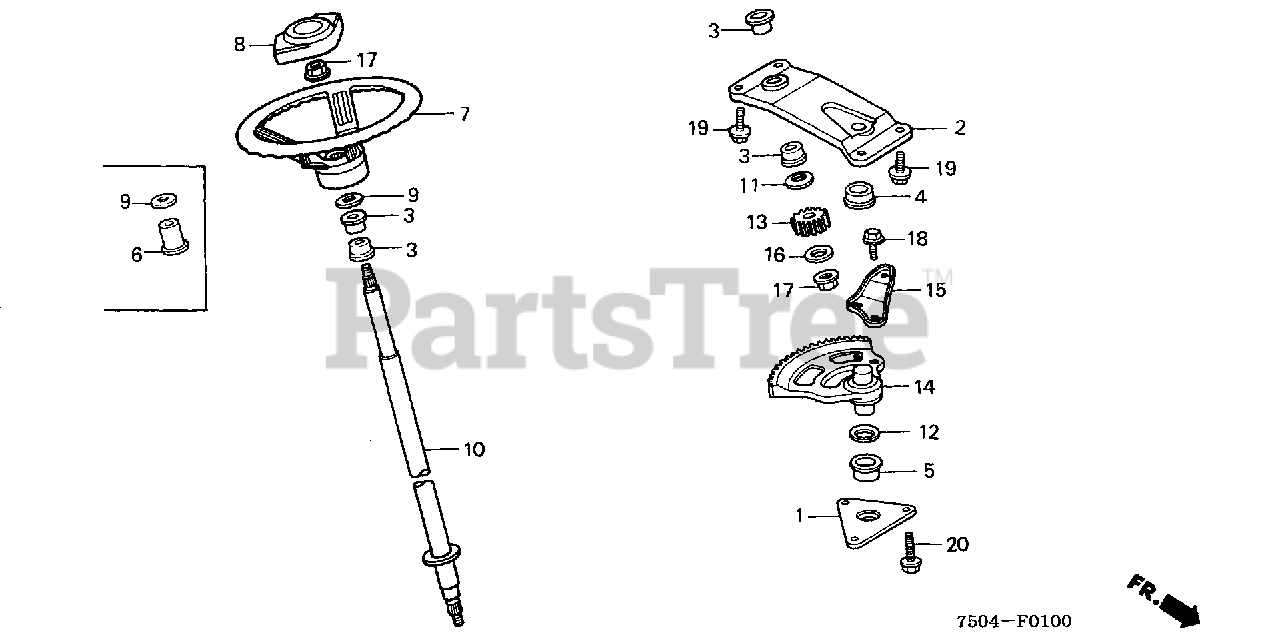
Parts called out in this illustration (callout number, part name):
1	HOLDER, STEERING GEAR
2	BOX, STEERING GEAR
3	BUSH (17X22X15)
4	BUSH (22X27X15)
5	BUSH (22X27X10) (NOT AVAILABLE)
6	BUSH (17X22X26)
7	WHEEL, STEERING
8	PAD, CENTER
9	WASHER, STEERING COLUMN
10	SHAFT, STEERING
11	WASHER B, STEERING GEAR
12	WASHER A, STEERING GEAR
13	GEAR, STEERING DRIVE
14	GEAR, STEERING DRIVEN (NOT AVAILABLE)
15	ARM, TIE ROD
16	WASHER, PLAIN (12MM)
17	NUT, SELF-LOCK
18	BOLT, FLANGE (8X18)
19	BOLT, FLANGE (8X20)
20	BOLT, FLANGE (8X25)
